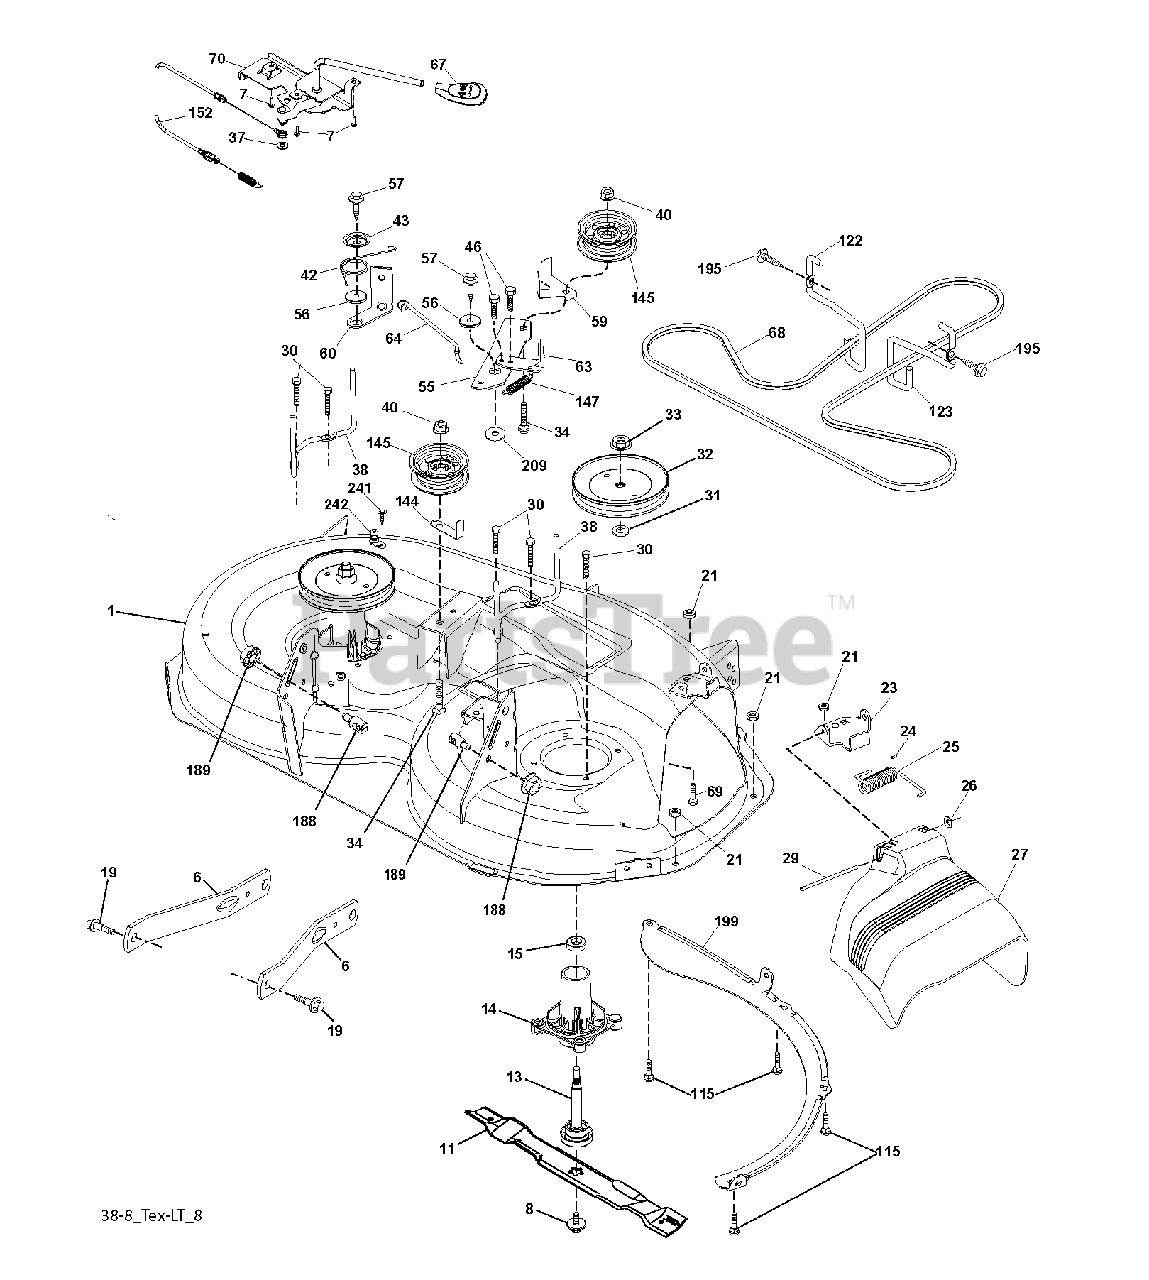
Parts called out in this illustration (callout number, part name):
6	ARM.SUSPENSION.MOWER.R
7	SCREW.#10 X 0.750.BOS THREAD
8	BOLT.WASHER.ASM.7/16-2
13	SHAFT.ASM.MDRL.N/GREASE.38
14	HOUSING MANDREL
15	BEARING
19	BOLT.SHOULDER
23	BRKT.DEFLECTOR.38"2005
24	CAP-SLEEVE LT
25	SPRING.TORSION.DEFLECT
26	NUT PUSH M
29	HINGE ROD
30	SCREW, WASHER HEAD
33	NUT.FLANGE.LOCK.TOP
37	WASHER
46	SCREW 1/4-20X5/8
55	IDLER.ARM
56	SPACER.RETAINER
57	SCREW 3/8-16X1
59	GUARD
69	BOLT
115	BOLT
145	PULLEY.IDLER.48"PRIMARY
147	SPRING RETURN
188	STUD.FASTNER.W/D.ANTI-
189	NUT LOCK HEX FLANGE 5/16-18
195	SCREW, 3/8-16X3/4
242	PORT.WASHOUT
